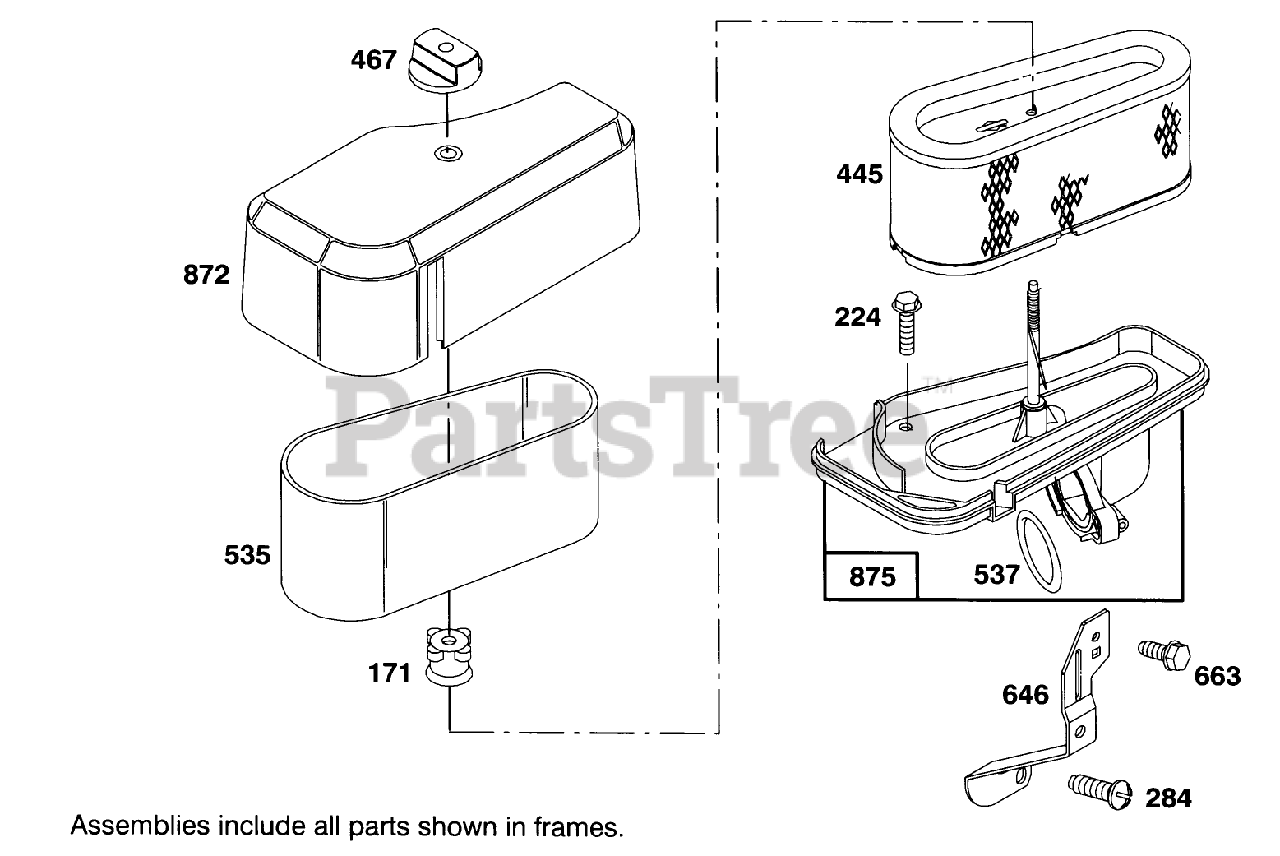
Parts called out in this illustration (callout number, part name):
224	Screw-Sem
284	Screw-Pan Head
445	Filter-Air
535	Filter-Air
537	O-Ring
646	Brace-Air Cleaner
663	Screw
872	Cover-Air Cleaner
875	Base-Air Cleaner
